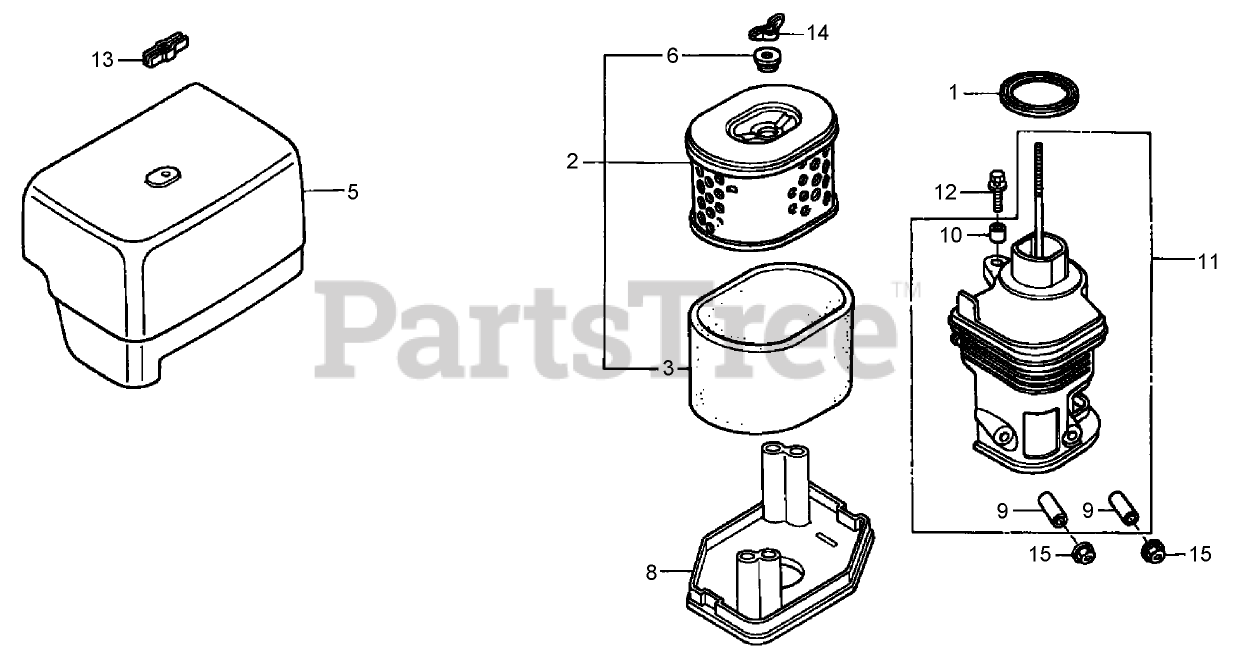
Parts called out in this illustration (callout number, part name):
1	GASKET-ELBOW
2	ELEMENT-AIR CLEANER
3	FILTER (OUTER)
5	COVER-AIR CLEANER
6	GROMMET-CLEANER, AIR
8	NOSE-MUFFLER
9	COLLAR-AIR CLEANER
10	COLLAR B-AIR CLEANER
11	ELBOW-AIR CLEANER
12	BOLT-WASHER (6X22)
13	WINGNUT (6MM)
14	WINGNUT
15	NUT-FLANGE (6 mm)
